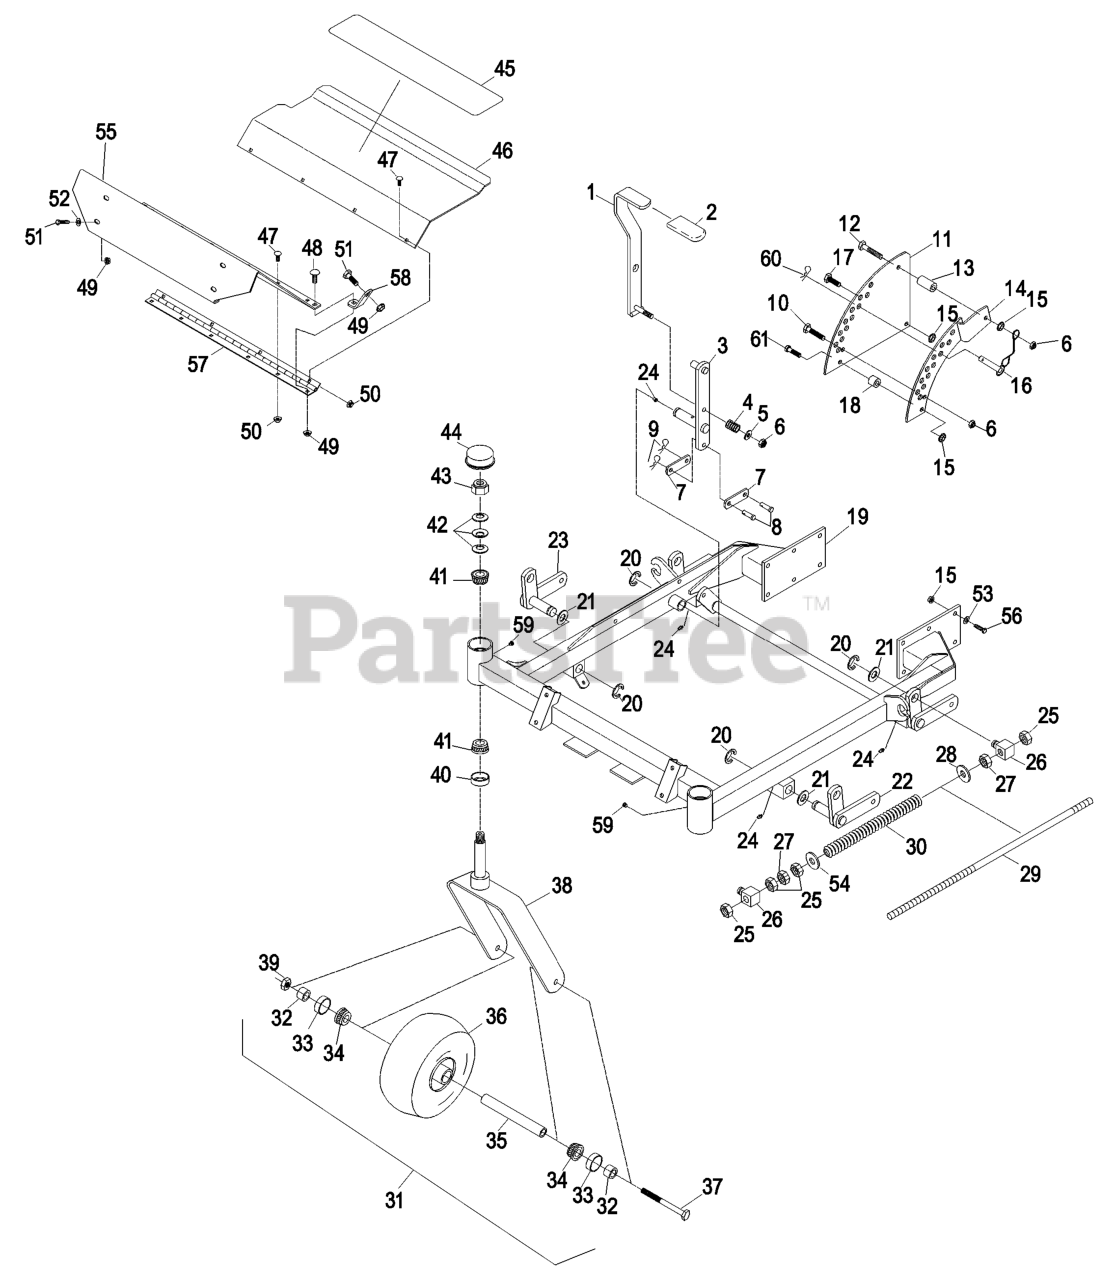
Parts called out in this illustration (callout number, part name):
2	GRIP-LEVER, LIFT
3	ARM-DECK, LIFT
4	SPRING-COMPRESSION
5	WASHER-FLAT
6	NUT-LOCK, NI
7	ARM-LIFT, DECK
8	PIN-CLEVIS
9	PIN-COTTER
10	SCREW-HH
11	PLATE-LIFT, DECK
12	SCREW-HH
13	BUSHING-LEVER, LIFT
14	PLATE-LIFT, DECK
15	NUT-HHF, WHIZ
16	PIN-HITCH (W/LANYARD)
17	SCREW-HH
18	BUSHING-LEVER, LIFT
19	ASM,44/48 FRONT FRAME SER
20	RING-RETAINING, EXT
21	WASHER-FLAT
22	WLD,SHAFT LH
23	WLD,SHAFT RH
24	FITTING-GREASE
25	NUT-HEX
26	SWIVEL-DECK MOUNT, REAR
27	Jam Nut, 5/8-11
29	ROD-LIFT, DECK
30	SPRING-COMPRESSION
32	SPACER-BEARING
33	SEAL-CASTER
34	BEARING-CONE, TAPERED ROLLER
35	SPACER-CASTER, FRONT
37	SCREW-HH
39	NUT-HEX
40	SEAL-GREASE
41	Cone-Bearing Tapered Roller
42	WASHER-BELLVILLE
43	NUT-LOCK, NI
44	CAP-GREASE
45	PAD-ANTISKID
47	SCREW-CARR
48	BOLT-CARR
51	SCREW-HH
52	WASHER-FLAT
53	WASHER-BELLEVILLE
54	WASHER-FLAT
56	SCREW-HH
57	HINGE-FLOORPAN
58	Bracket, Floorpan
60	PIN-COTTER
61	SCREW-HH
